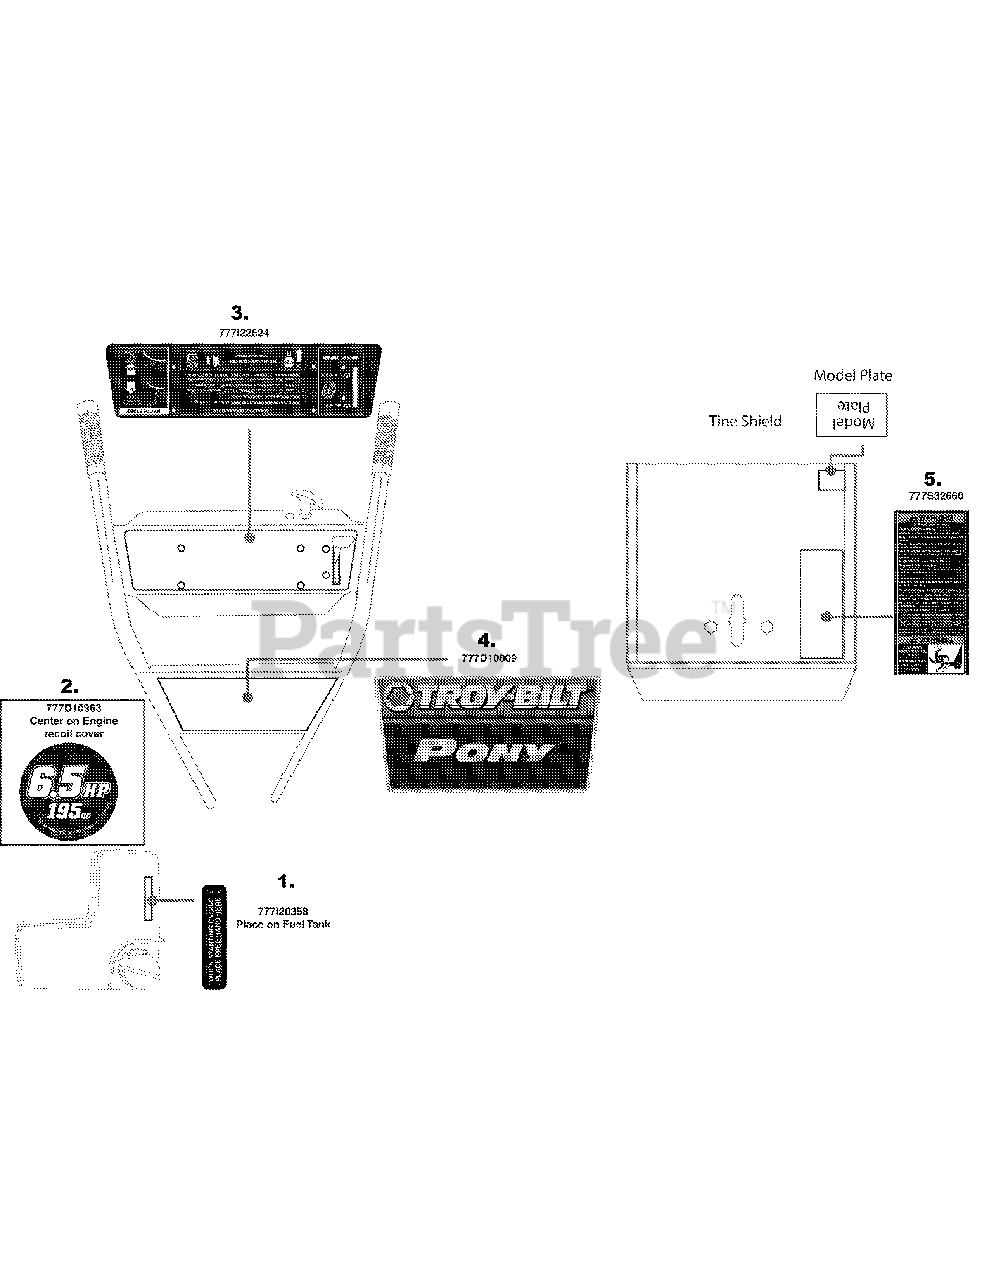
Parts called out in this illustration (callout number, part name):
1	LABEL-PLACE HAND HERE
2	LABEL-ENGINE
3	LABEL:TILLER HANDLE:660
4	LABEL-TILLER HANDLE PANEL:PONY
5	LABEL:TILLER TINE SHIELD
